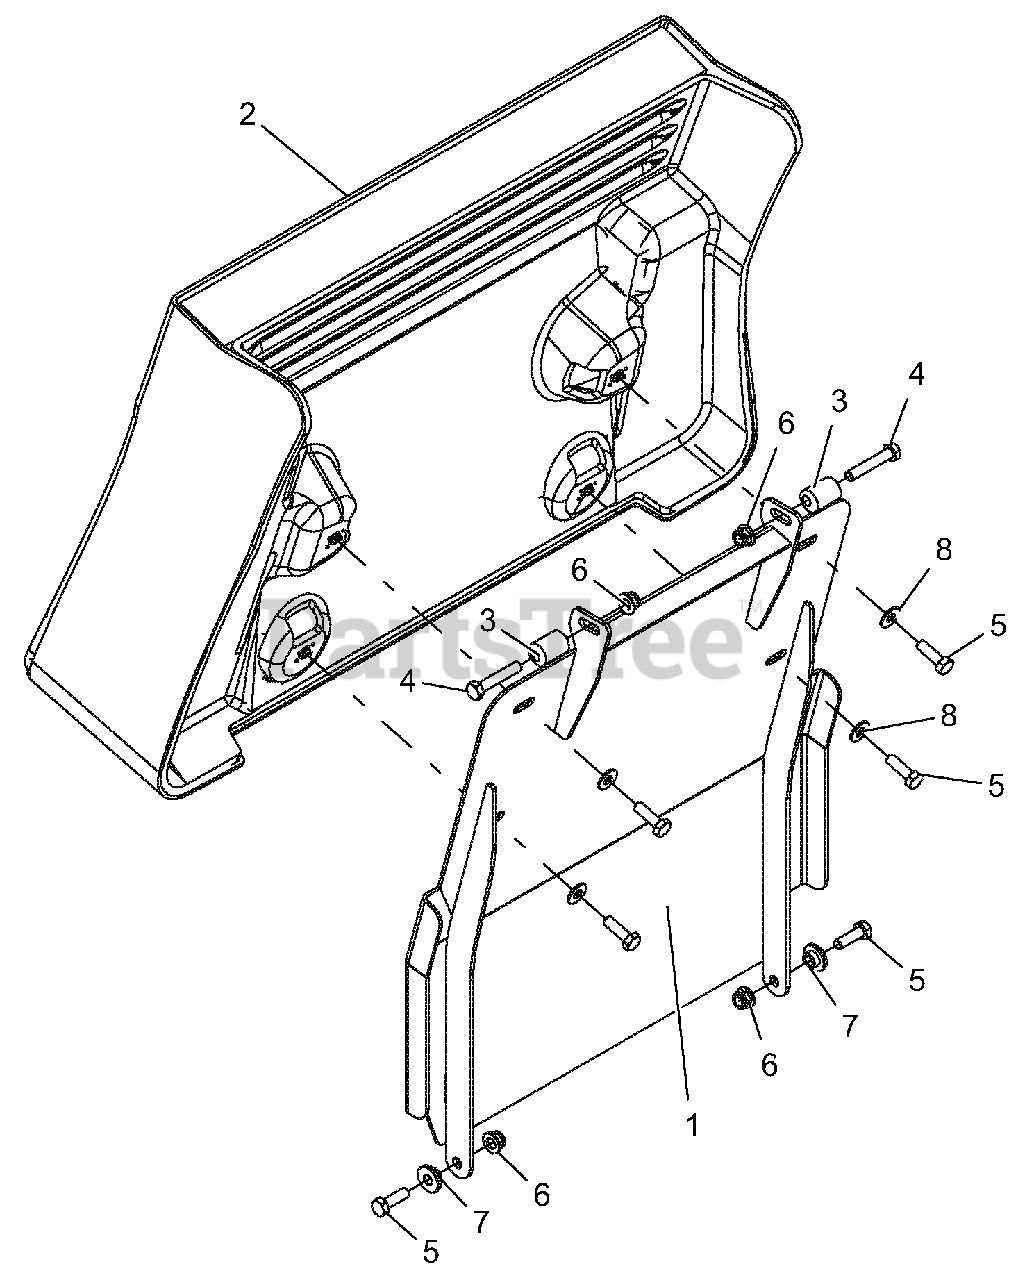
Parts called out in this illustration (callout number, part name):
1	WLDMT, PAD MOUNT
2	PAD, PROSTANCE
3	ECCENTRIC
4	BLT-HEX .31-18X1.75 GR5 YWZC
5	BLT-HEX .31-18X1.00 GR5 YWZC
6	NUT-LK-NYL-FLG .31-18 YWZC
7	BSHG, FLG .32X.500.344X.880
8	WSHR-FL-STL.312X.734X.065 YWZ
